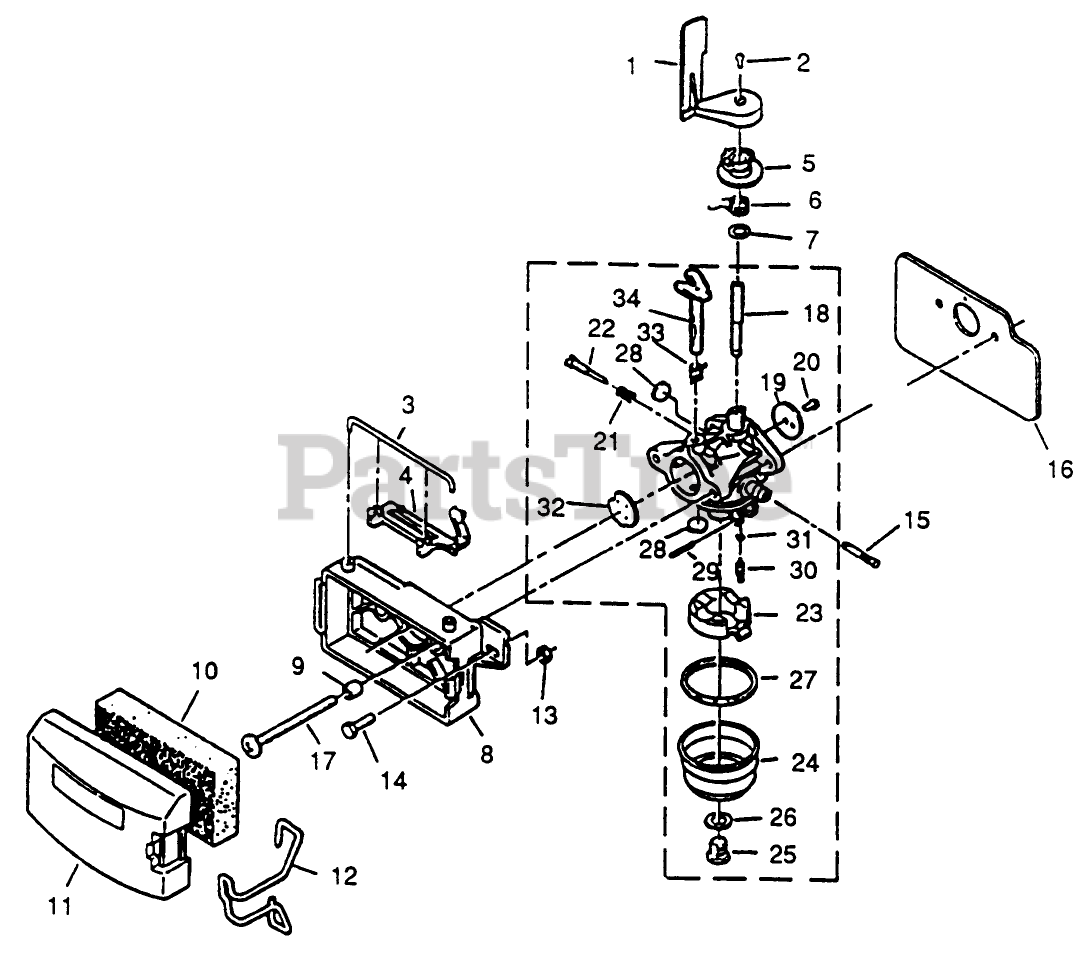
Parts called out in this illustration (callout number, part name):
1	AIR VANE F
2	SCREW F
3	RETAINER
5	COLLAR A/VAVE F
6	THROTTLE SPR E
7	WASHER VF
9	SPACER
12	RETAINER-COVER, FILTER
14	SCREW
15	SCREEN FUEL PITTS
16	Heat Shield
17	SCREW
18	Throttle Shaft
19	Throttle Valve
20	Screw-Throttle Valve
21	Spring-Idle Needle
22	Idle Needle
24	Fuel Bowl
25	Screw-Bowl Retainer
26	Bowl Retainer Gasket
27	Fuel Bowl Gasket
28	Plug-Welch
29	Float Shaft
30	Inlet Needle Valve
31	Valve Seat
32	Choke Valve
33	Choke Return Spring
34	Choke Shaft
